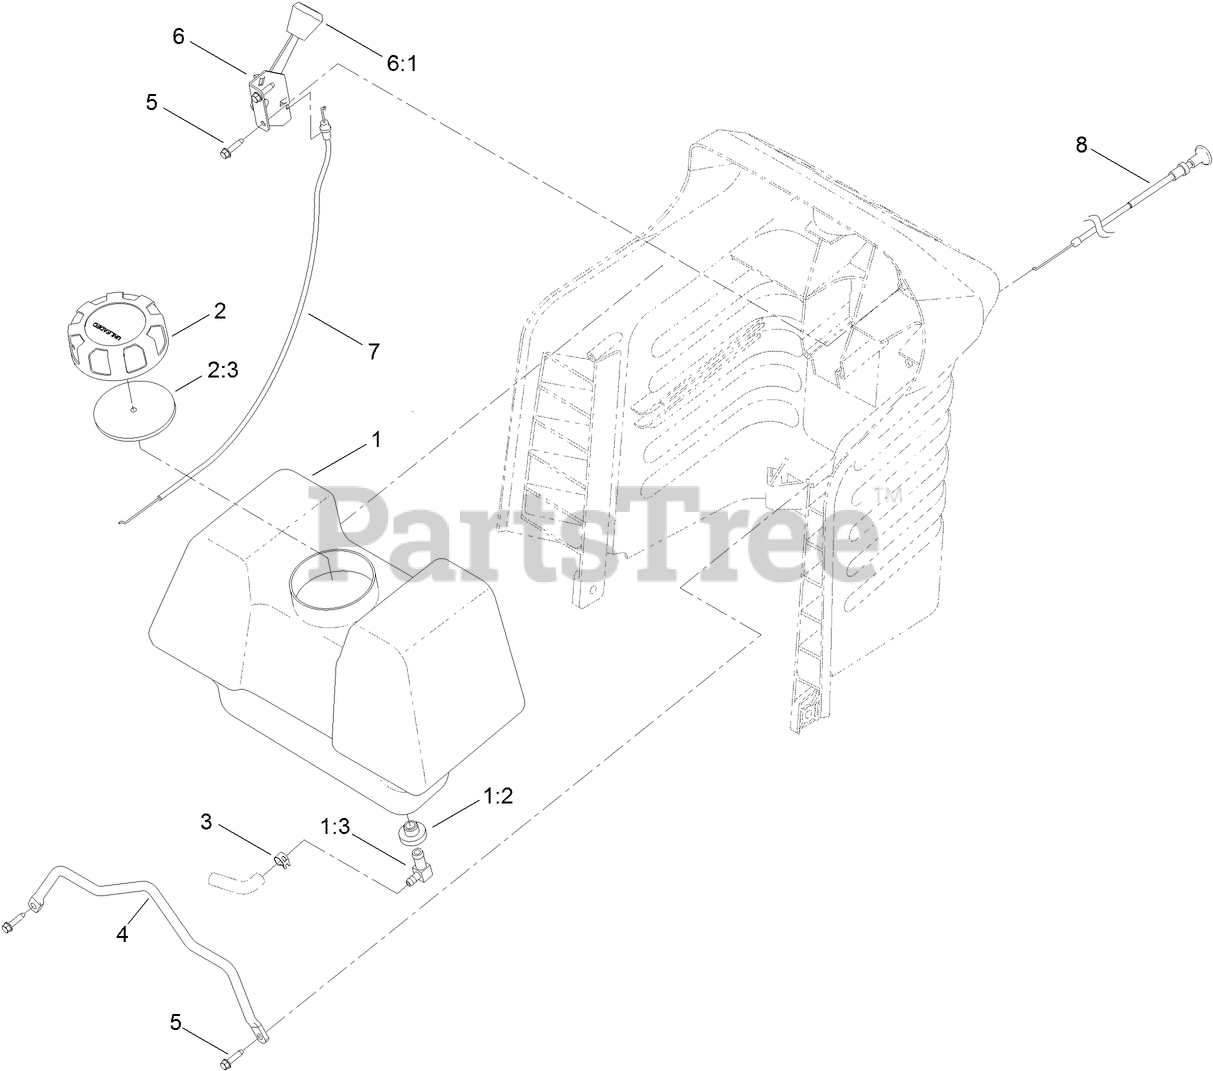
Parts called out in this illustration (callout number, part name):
1	GAS TANK ASM
1:2	BUSHING
1:3	VALVE-FUEL
2	GAS CAP ASM
2:3	GASKET-CAP, GAS
3	CLAMP-HOSE
4	ROD-TANK, GAS
5	SCREW-SPECIAL
6	THROTTLE CONTROL ASM
7	CABLE-THROTTLE
8	CHOKE CONTROL ASM
